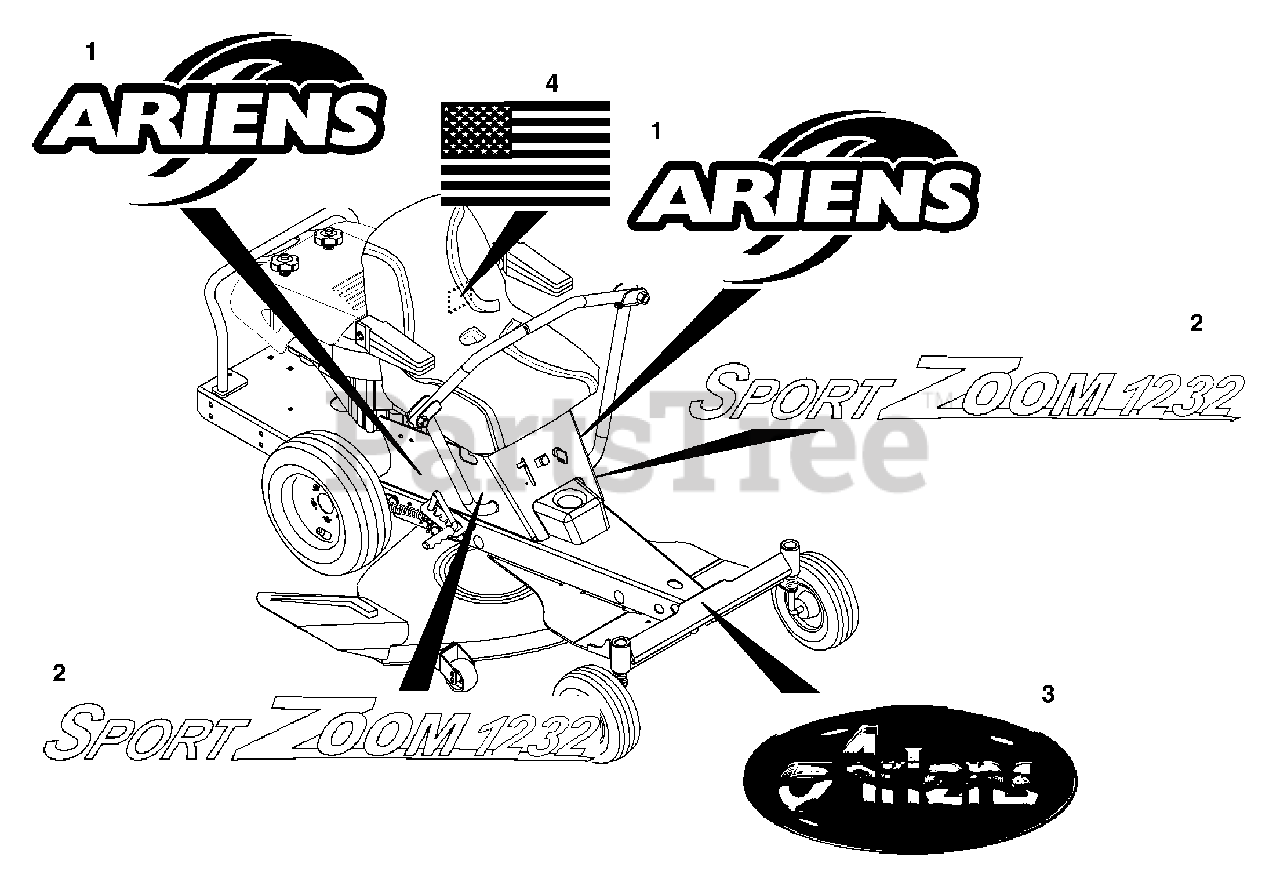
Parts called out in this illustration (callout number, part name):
1	DECAL-ARIENS ZOOM
2	DECAL-SPORT ZOOM 1232
3	DECAL-ARIENS JEWEL
4	DECAL, AMERICAN FLAG
